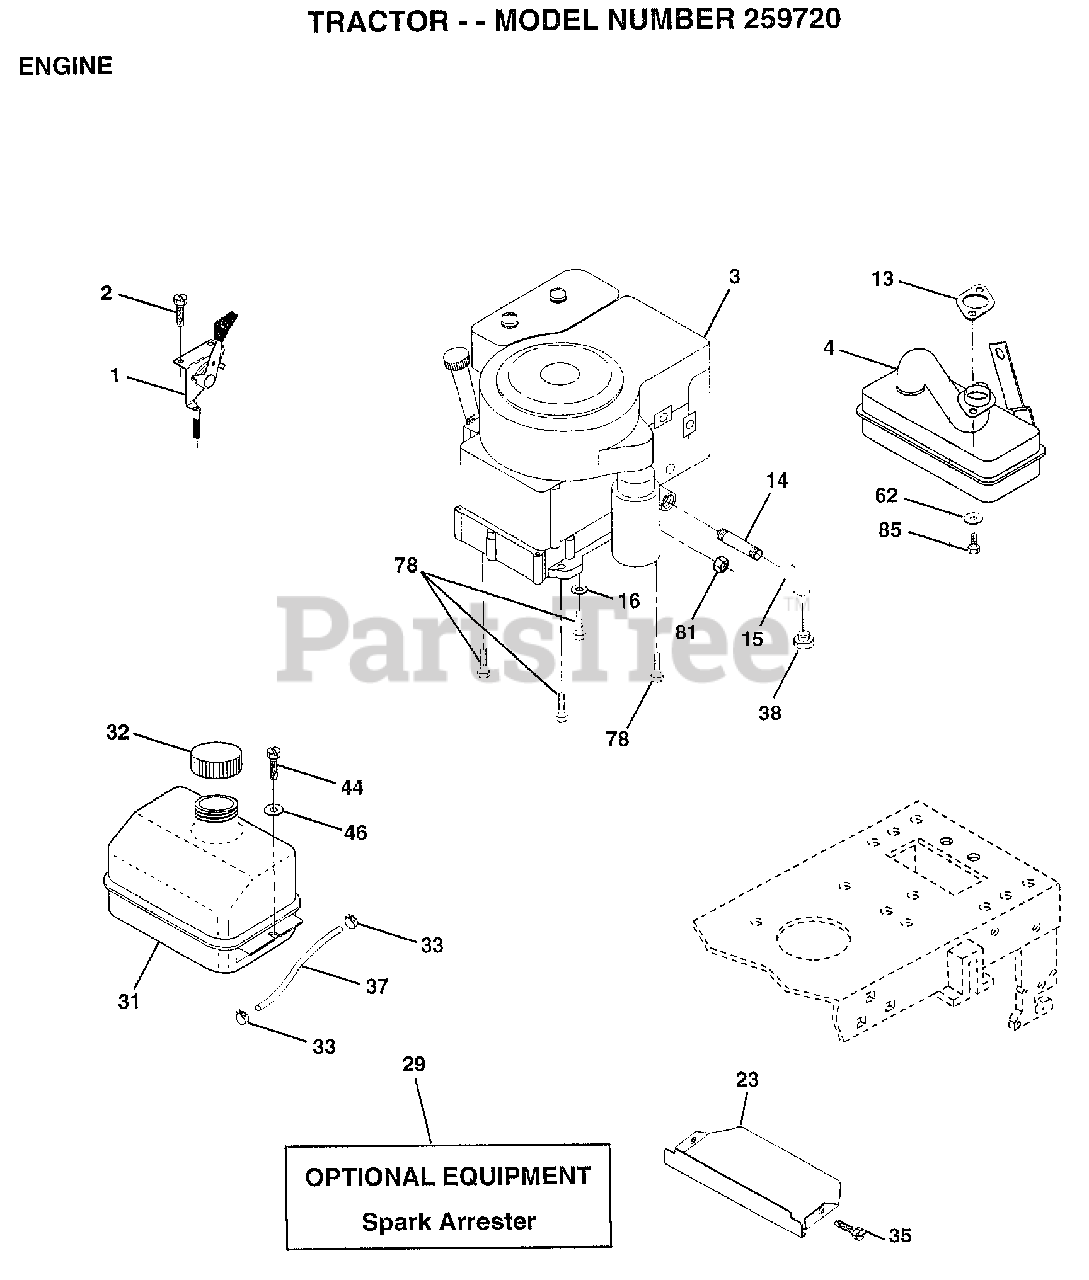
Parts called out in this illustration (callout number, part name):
1	CONTROL-THROT/CHO
2	SCREW LT
4	MUFFLER TEC. 13HP
14	PIPE NIPPLE LT
15	ELBOW
16	LOCKWASHER
23	SHIELD.BRN/DBR.GD
31	TANK.FUEL.LT.
32	CAP ASM FUEL
33	HOSE CLAMP
35	SCREW
37	LINE FUEL
44	SCREW HEX CRT
46	WASHER
62	LOCKWASHER
72	SCREW
78	SCREW
81	NUT
85	SCREW HEX HD CAP
